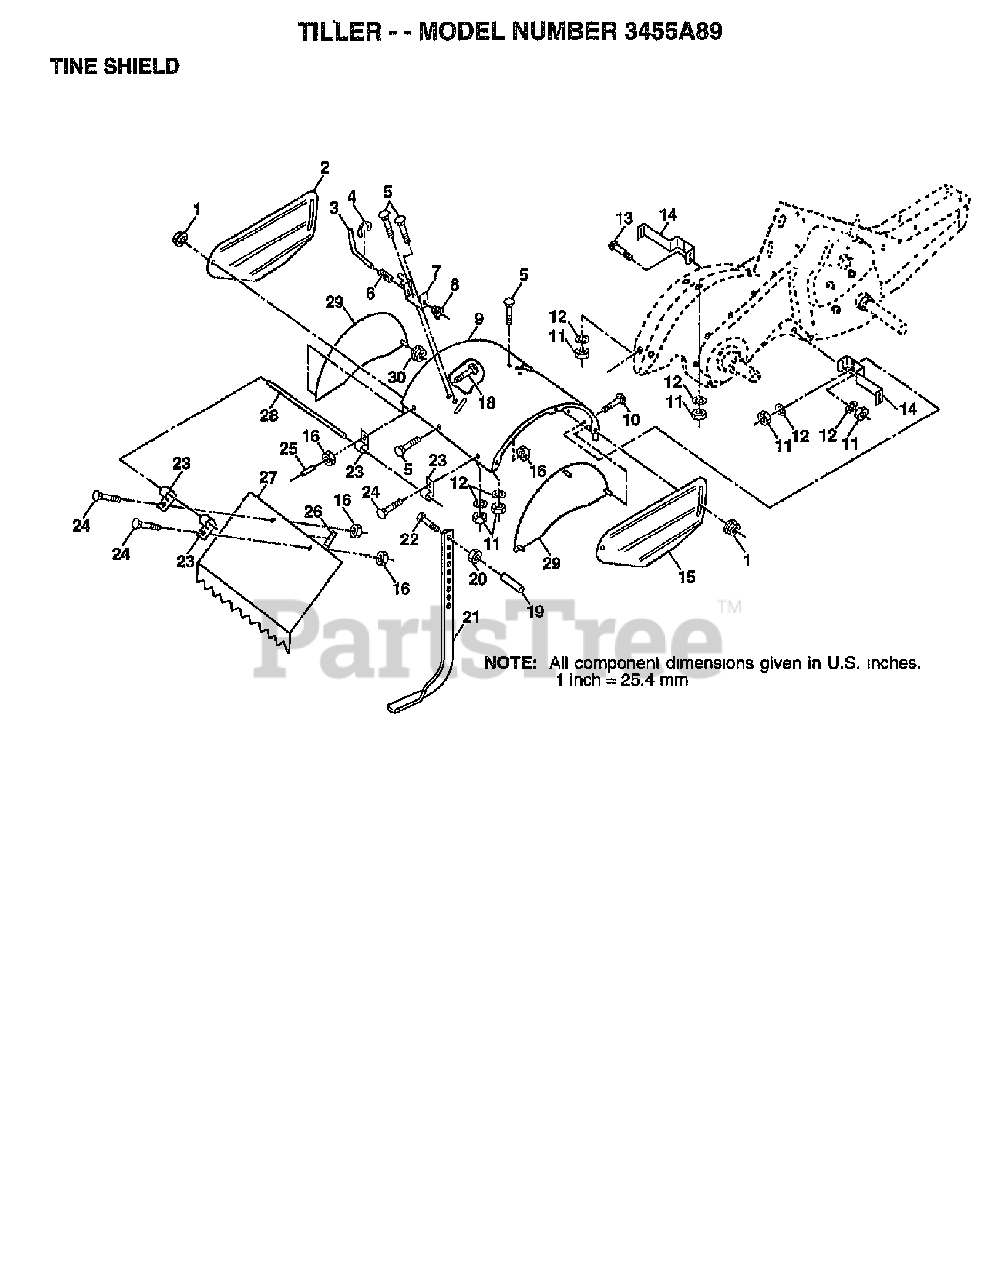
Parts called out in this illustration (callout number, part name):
2	SHIELD LH
3	STAKE PIN TI
4	KLIP RING TI
5	BOLT
6	SPRING TI
7	LATCH BRACKET TI
8	SPRING CRT
9	SHIELD.TINE.BLACK
10	BOLT
12	LOCKWASHER
13	BOLT.CARRIAGE.5/16-18
14	BRACKET.TINE.SHIELD.TILLER.BLA
15	SIDE SHIELD RH
16	NUT
19	GRIP CRT
20	NUT.HEX.3/8-16UNC
21	STAKE.DEPTH.16.CRT.BLACK
22	BOLT
23	HINGE CRT
25	VINYL CAP
26	PAD IDLER TI
27	SHIELD LEVELING
28	PIN.HINGE.TILLER
29	Tiller Side Shield Kit, Black
30	LOCKNUT-FLANGE 5/16-18
